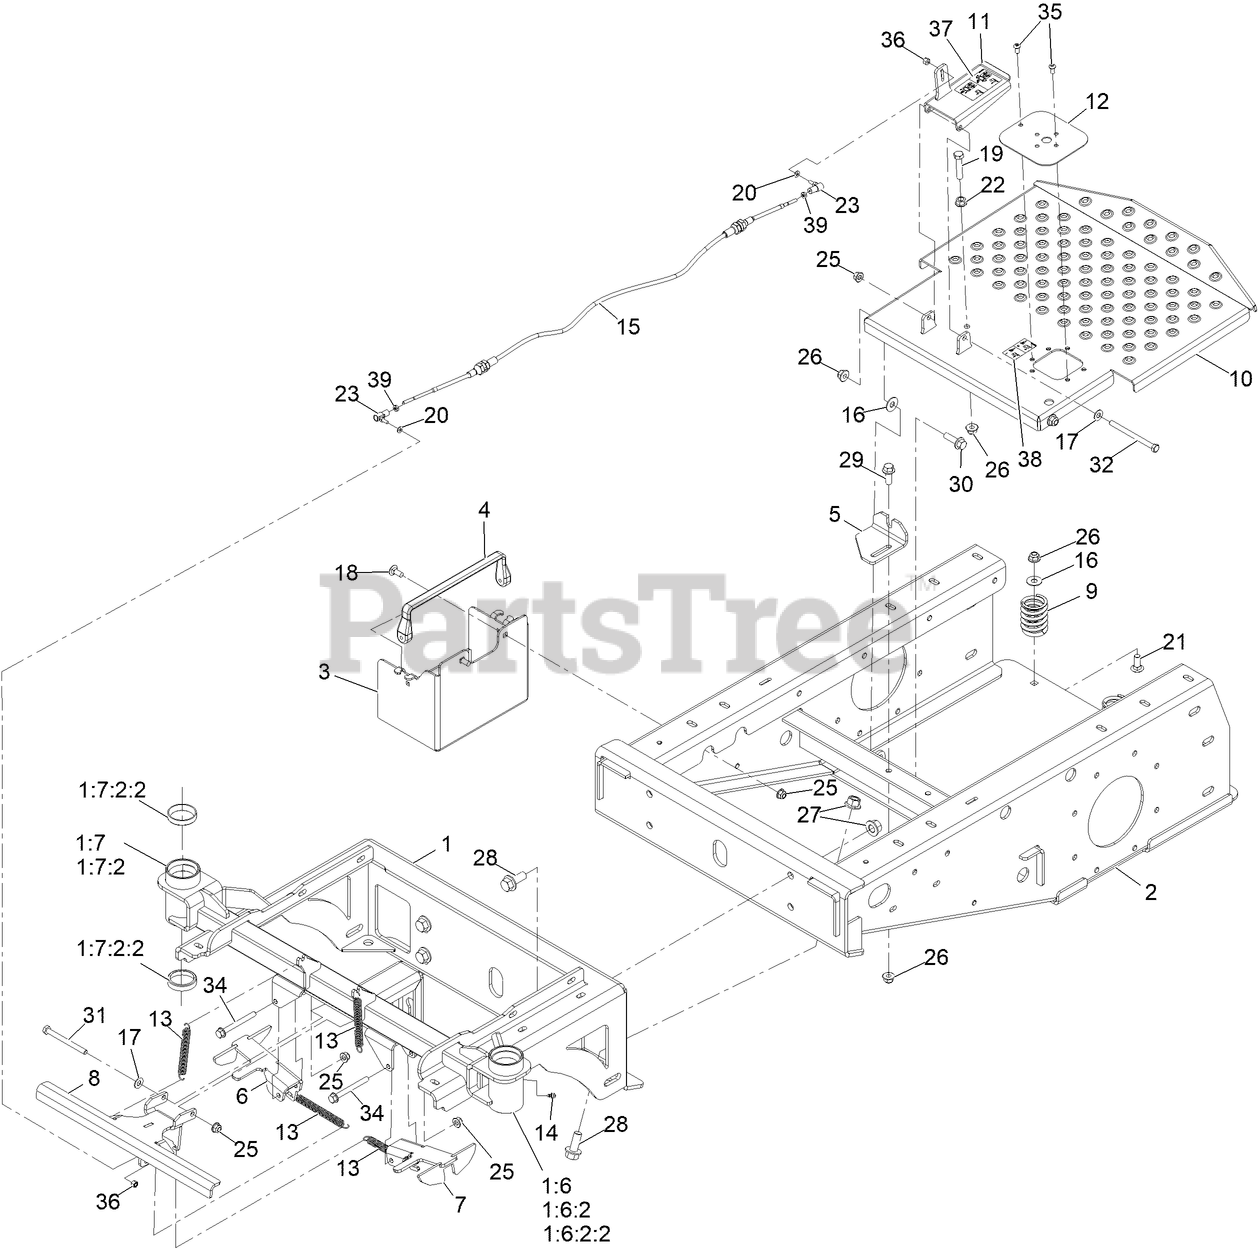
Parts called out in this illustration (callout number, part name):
1	Frame-Front
1:6	Tube-Caster, Lt
1:6:2	Tube-Caster, W/Cup
1:6:2:2	BEARING-CUP, TAPERED
1:7	Tube-Caster, Rt
1:7:2	Tube-Caster, W/Cup
1:7:2:2	BEARING-CUP, TAPERED
2	FRAME-REAR
3	BOX-BATTERY
4	BUNGEE (TARP STRAP)
5	Bracket, Lower Cable
6	Wing-Capture, Rt
7	Wing-Capture, Lt
8	Capture-Lcs
9	SPRING-COMPRESSION
10	PLATE-FOOT
11	Pedal-Foot
12	Panel, Foot Switch
13	SPRING-EXTENSION
14	FITTING-GREASE, ZERK
15	CABLE-CASTER, LOCKING
16	WASHER-FLAT
18	SCREW-CARR
19	Screw-HH
20	WASHER-FLAT
21	SCREW-CARR
22	Nut-Hex Flange
23	BALL JOINT-SS
25	Nut-Hex Flange
26	Nut-Hex Flange
27	NUT-HEX FLANGE
28	SCREW-HHF
29	SCREW-HHF
30	SCREW-HHF
31	SCREW-HH
32	Screw-HH
34	SCREW-HHF
35	Screw-HSBH
36	Nut,NYL Lock,#10-32,ST/ST 18-8
37	Decal-Lock, Caster
38	Decal-Spray Foot Button
39	Nut,Hex Jam Mch Scr,10-32,Sst
